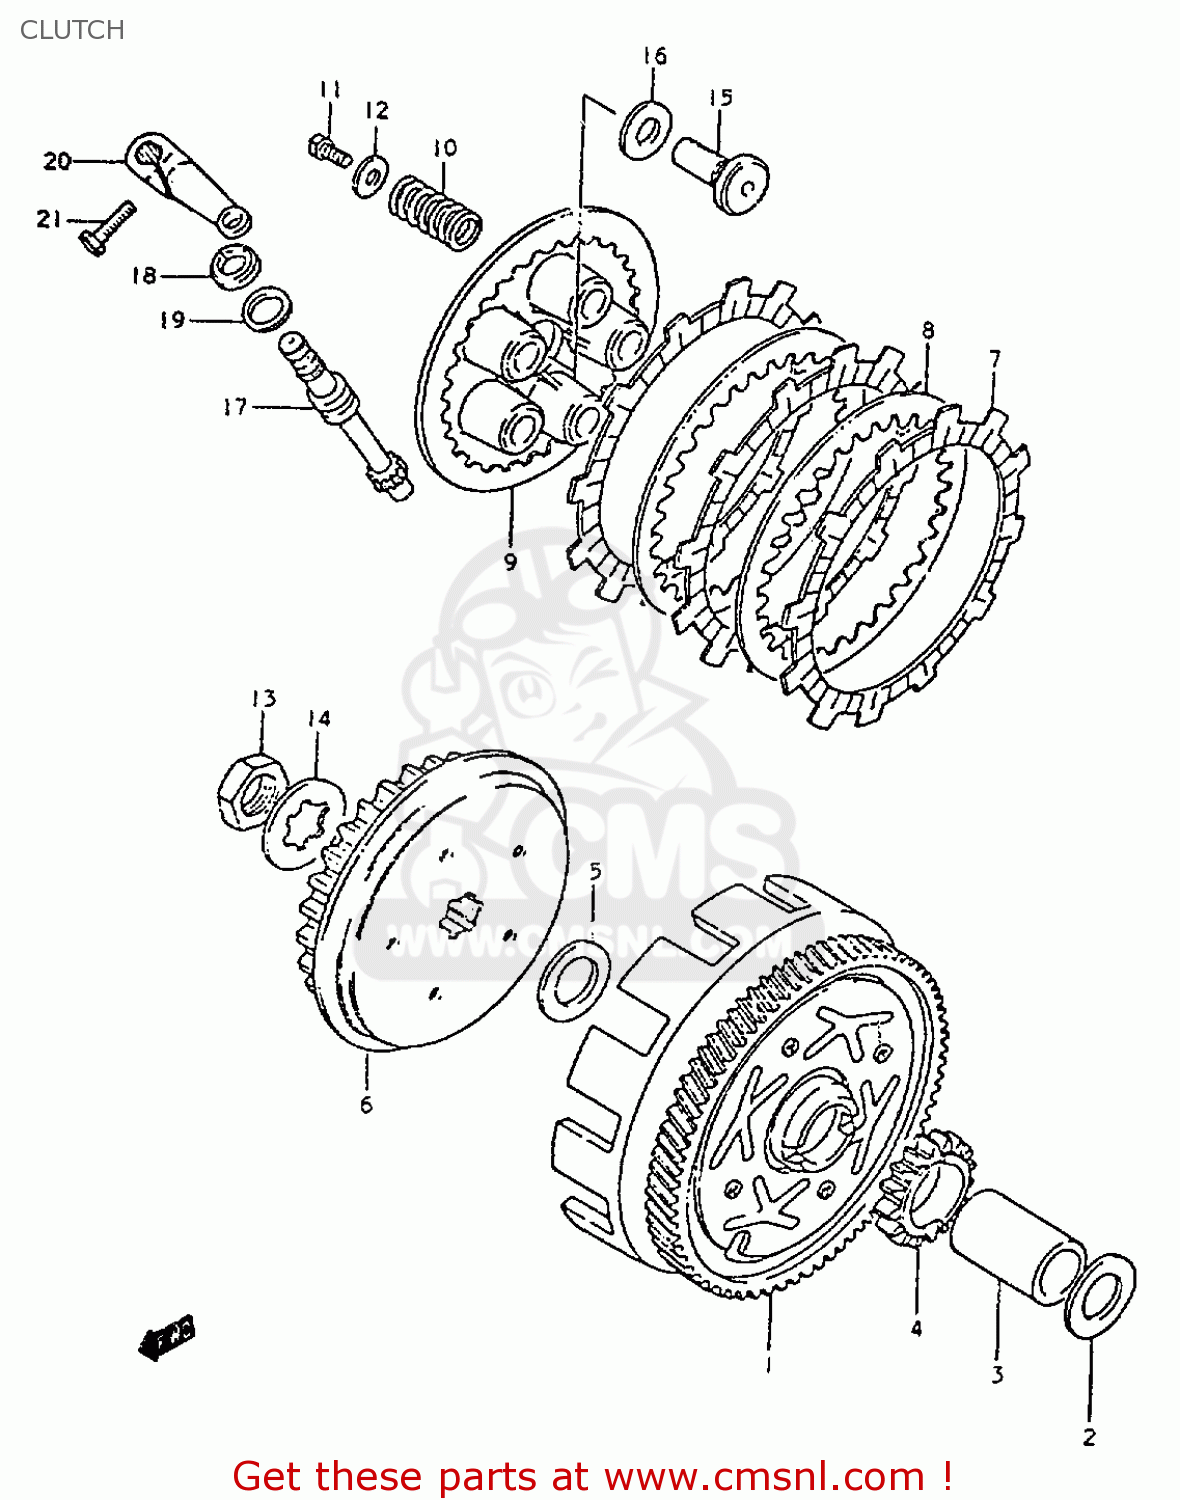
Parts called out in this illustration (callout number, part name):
1	GEAR ASSEMBLY,PRIMARY DRIVE
2	WASHER,THRUST
3	SPACER
4	GEAR,KICK STARTER DRIVE
5	WASHER
6	HUB,CLUTCH SLEEVE
7	PLATE,CLUTCH DRIVE
8	PLATE,CLUTCH DRIVEN (NAS)
9	DISC,CLUTCH PRESSURE
10	SPRING
11	BOLT(5X16)
12	WASHER (5.5X16X1.2)
13	NUT
14	WASHER,LOCK
15	RACK,CLUTCH RELEASE
16	BEARING(10X22X2.8)
17	PINION,CLUTCH RELEASE
18	OIL SEAL
19	WASHER (12X17X1)
20	ARM,CLUTCH RELEASE
21	BOLT, UPPER
